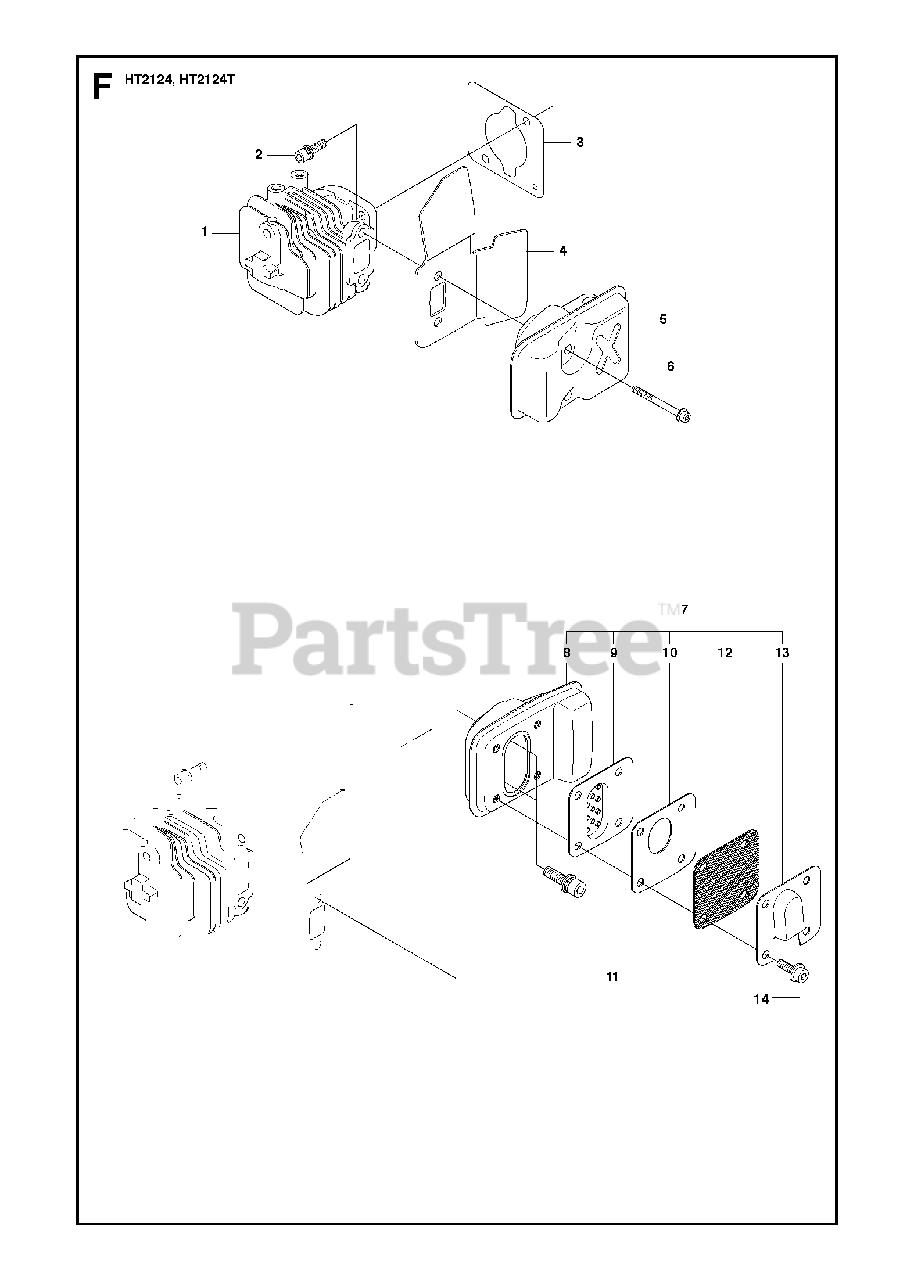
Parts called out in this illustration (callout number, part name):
1	CYLINDER/CARB
3	BASE GASKET
4	HEAT SHIELD/GASKET
7	MUFFLER ASSY
8	MUFFLER
9	BAFFLE PLATE
10	BAFFLE PLATE
12	SPARK ARRESTER
13	EXHAUST DEFLECTOR
